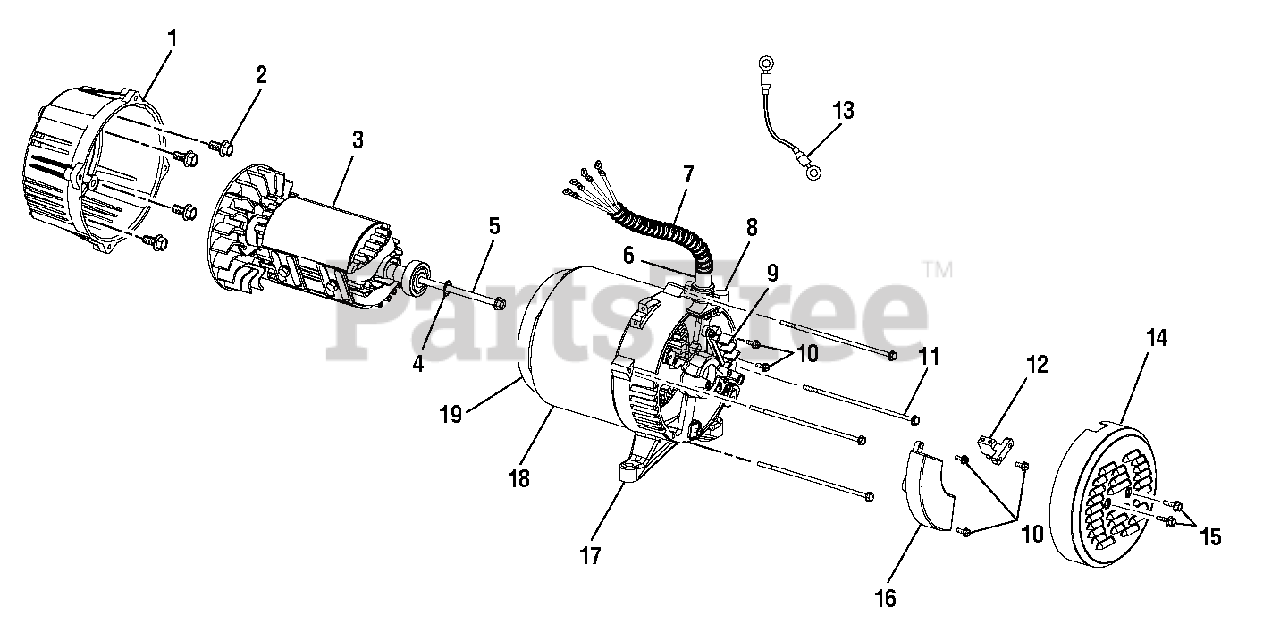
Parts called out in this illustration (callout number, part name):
1	Adaptor Housing
2	Bolt (3/8-16 X 1.25 in.)
4	Lock Washer (5/16)
5	Rotor Bolt
6	Rubber Boot
7	Wiring Harness
8	Generator Head Assembly
9	Terminal Block
10	Bolt (M5 x 16 mm)
11	Bolt (Stator
12	Brush Assembly
13	Bonding Wire
14	Brush Cover
15	Bolt (M5 x 10 mm)
16	Automatic Voltage Regulator
17	Bearing Housing
18	Generator Head Cover
